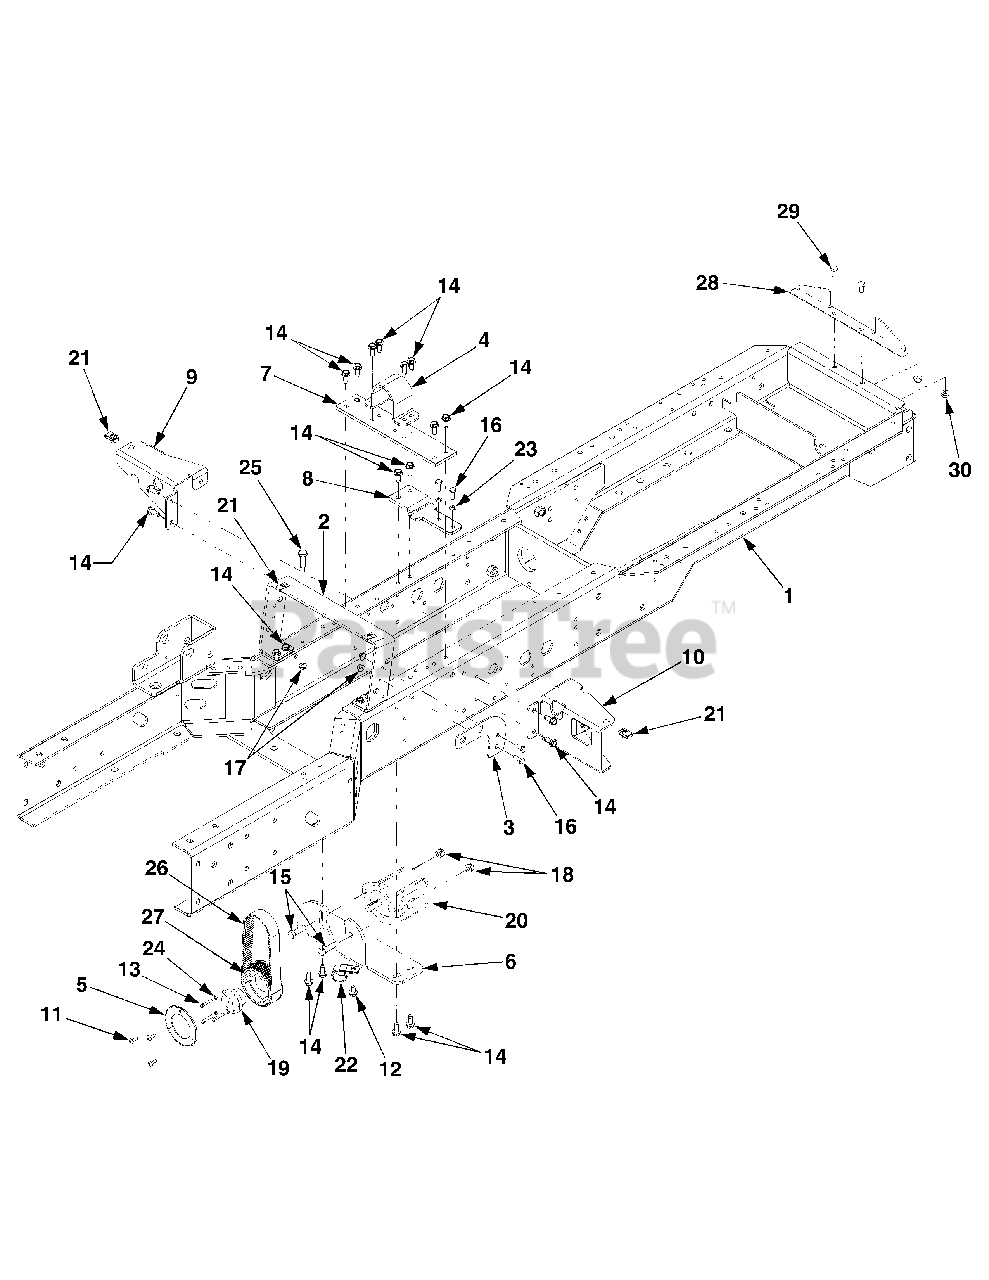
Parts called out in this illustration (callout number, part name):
2	Bracket, Front Seat Mount
3	Bracket, Fitting Mtg.
4	Shield, Drive Shaft
5	Keeper, Belt
6	Bracket, Aux. Pump Mtg.
7	Shield Lower Drive Shaft
8	Plate, Filter Mounting
9	Bracket, Running Board Mtg.
10	Bracket, Running Board Mtg.
11	Screw, Truss Hd. Mach. #10-24 x .5
12	Screw, Hex Wash. Hd Tapp 5/16-18 x .5
13	Screw, Hex Mach. #10-24 x 1.0 GR5
14	Screw, Hex Wash. Hd. Tapp, 5/16-18 x .75
15	Screw, Hex Cap, 3/8-16 x 1.25 GR5
16	Screw, Hex Cap, 1/4-20 x .75 GR5
17	Nut, Hex Nylon Flange Lock, 1/4-20 GRF
18	Nut, Hex Lock, 3/8-20 GrB
19	Bushing, Tapered
20	Pump, Aux. Hydraulic
21	Nut, U Speed, 5/16-18
23	Washer,Lock, 1/4
24	Washer, Lock, #10
25	Screw, Shoulder, .374 x 1.16
26	Belt, HTS, 5 x 25 x 500
27	Pulley, 52T Cog
29	Screw, Hex Cap, 5/16-18 x .625 GR5
30	Nut, Hex Flange Insert Lock, 5/16-16 GrF
